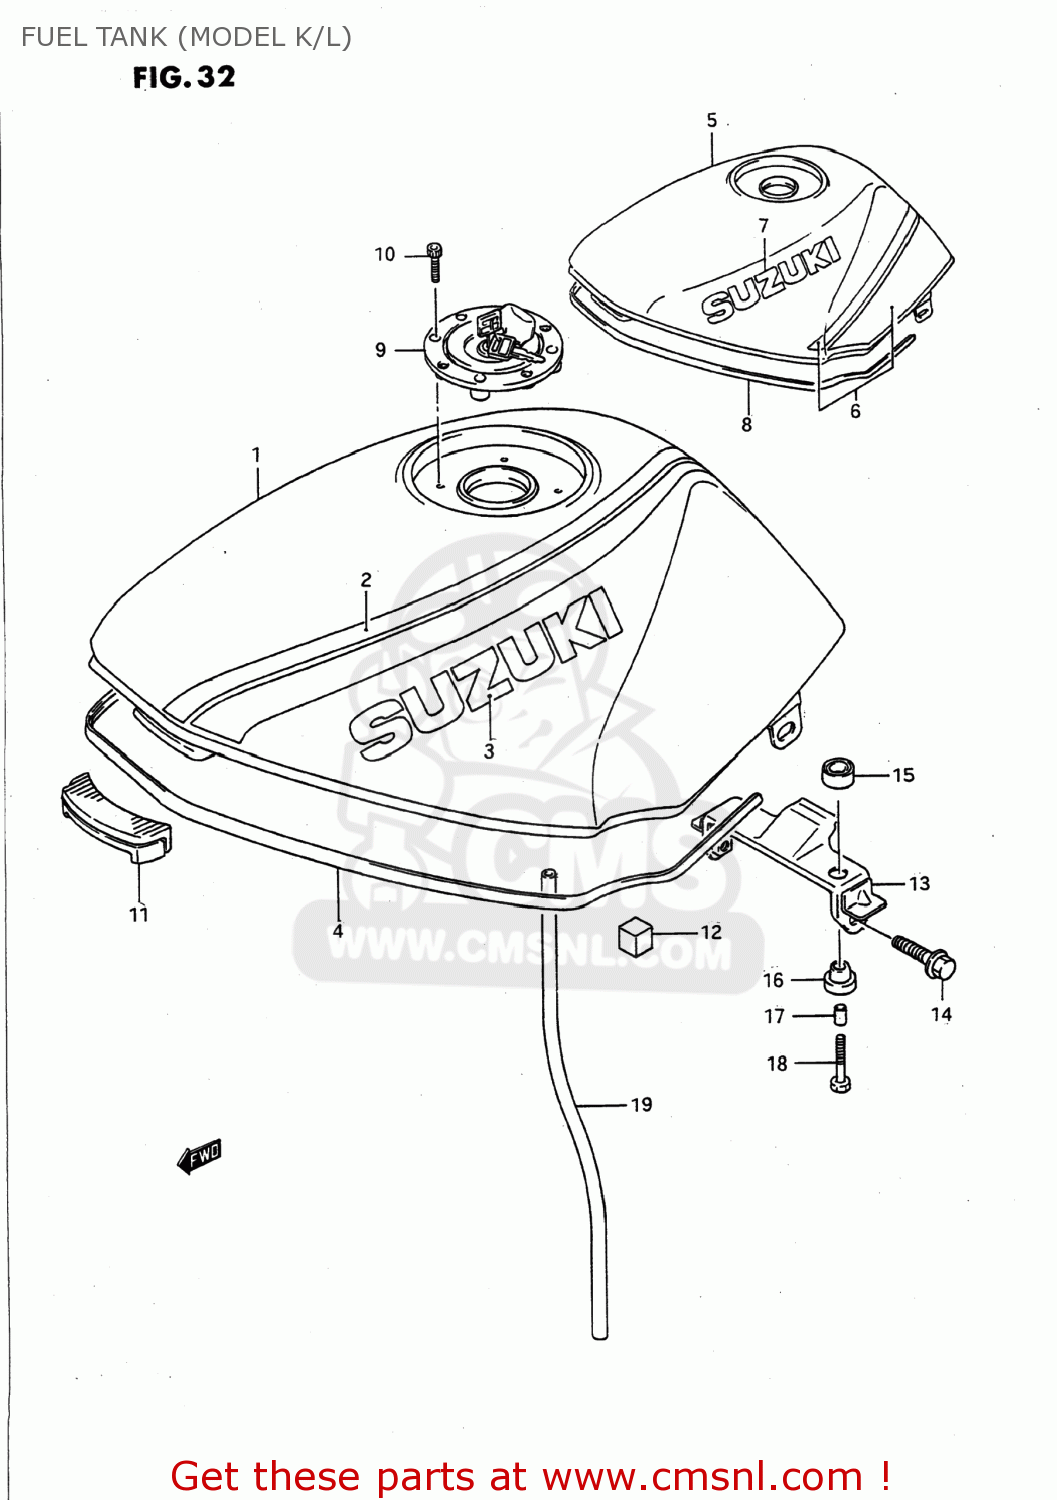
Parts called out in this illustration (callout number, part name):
1	TANK ASSEMBLY,FUEL
2	TAPE SET,FUEL TANK STRIPE
3	EMBLEM,FUEL TANK
4	MOLDING
5	TANK ASSEMBLY,FUEL
6	TAPE SET,FUEL TANK
7	EMBLEM,FUEL TANK
8	MOLDING
9	CAP SET,FUEL TANK
10	BOLT(5X20)
11	CUSHION,FUEL TANK FR
12	CUSHION,FUEL TANK SIDE
13	BRACKET COMP,FUEL TANK
14	BOLT
15	CUSHION
16	CUSHION
17	SPACER(6.1X9X18.2)
18	BOLT
19	HOSE,WATER DRAIN
